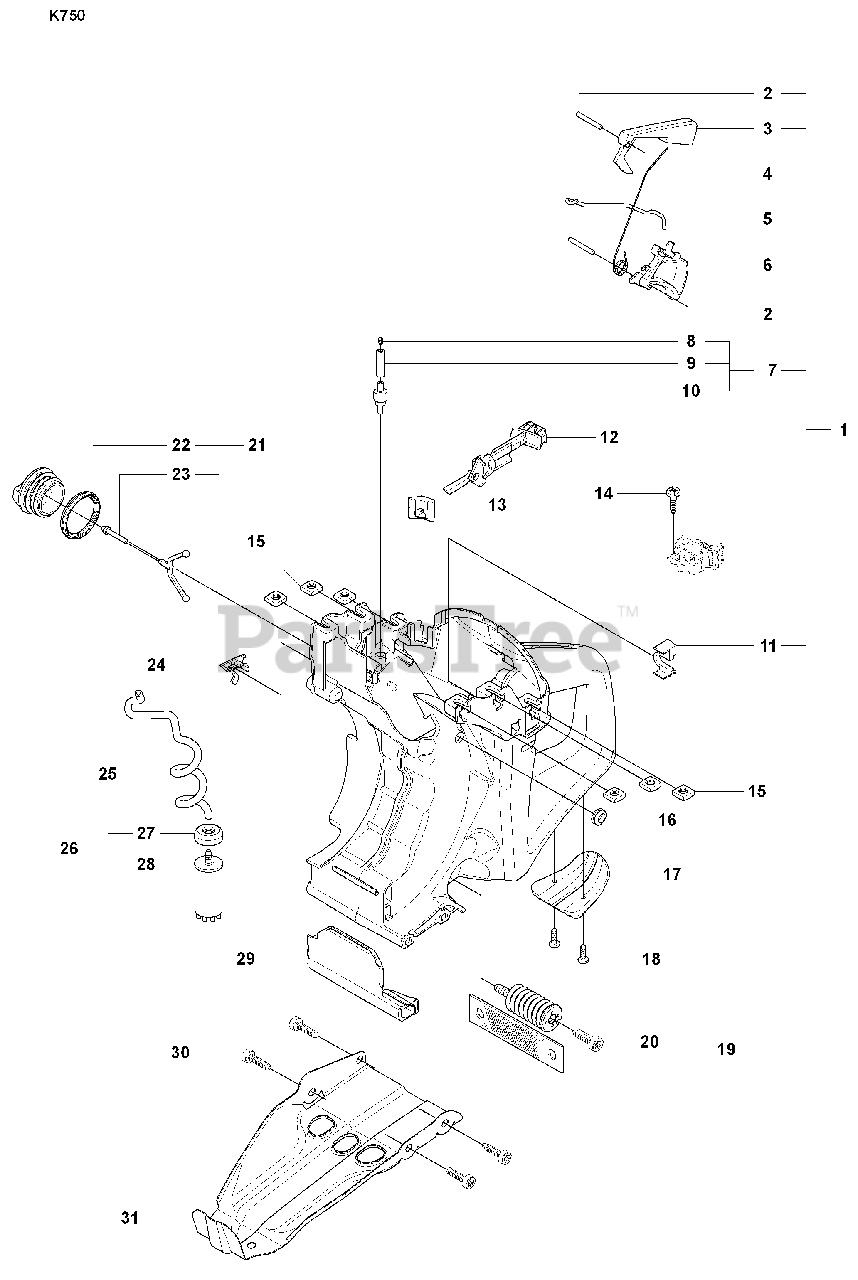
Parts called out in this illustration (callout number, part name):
1	FUEL TANK
2	PARALLEL PIN
3	THROTTLE LOCKOUT
4	SPRING
5	THROTTLE ROD
6	THROTTLE TRIGGER
7	TANK VENT ASSY
8	FILTER PLUG
12	CHOKE CONTROL
14	SCREW CCRPANT
16	CABLE GROMMET
17	GROUND SUPPORT
19	AV-ELEMENT
21	TANK CAP ASSY
24	CAP
25	FUEL HOSE
26	FUEL FILTER
27	HOSE CLAMP
28	FUEL FILTER
29	HEAT SHIELD
31	BASE PLATE
